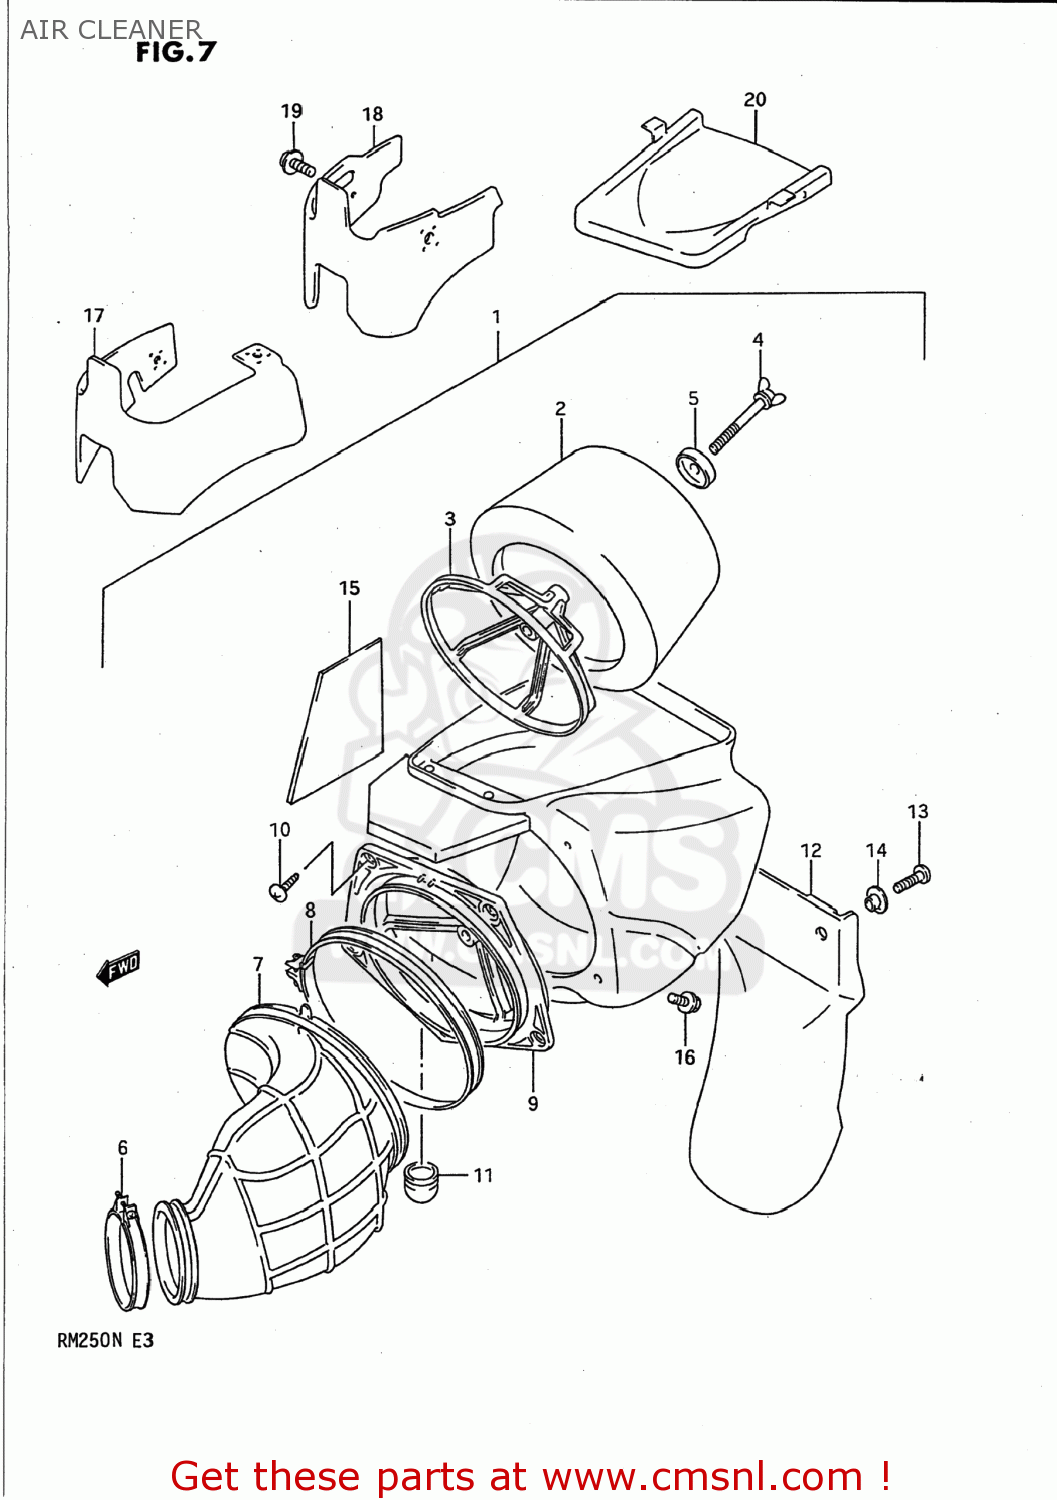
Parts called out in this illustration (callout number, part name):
1	CLEANER ASSEMBLY,AIR
2	FILTER
3	HOLDER,FILTER
4	BOLT,WING
5	WASHER,AIR CLEANER
6	CLAMP
7	TUBE,OUTLET
8	CLAMP
9	HOLDER,FILTER
10	SCREW
11	TUBE,DRAIN
12	GUARD,MUD
13	SCREW
14	COLLAR
15	TRAP,HEAT
16	BOLT
17	GUARD,MUD,C
18	GUARD,MUD
19	SCREW(6X12)
20	CAP,AIR CLEANER
